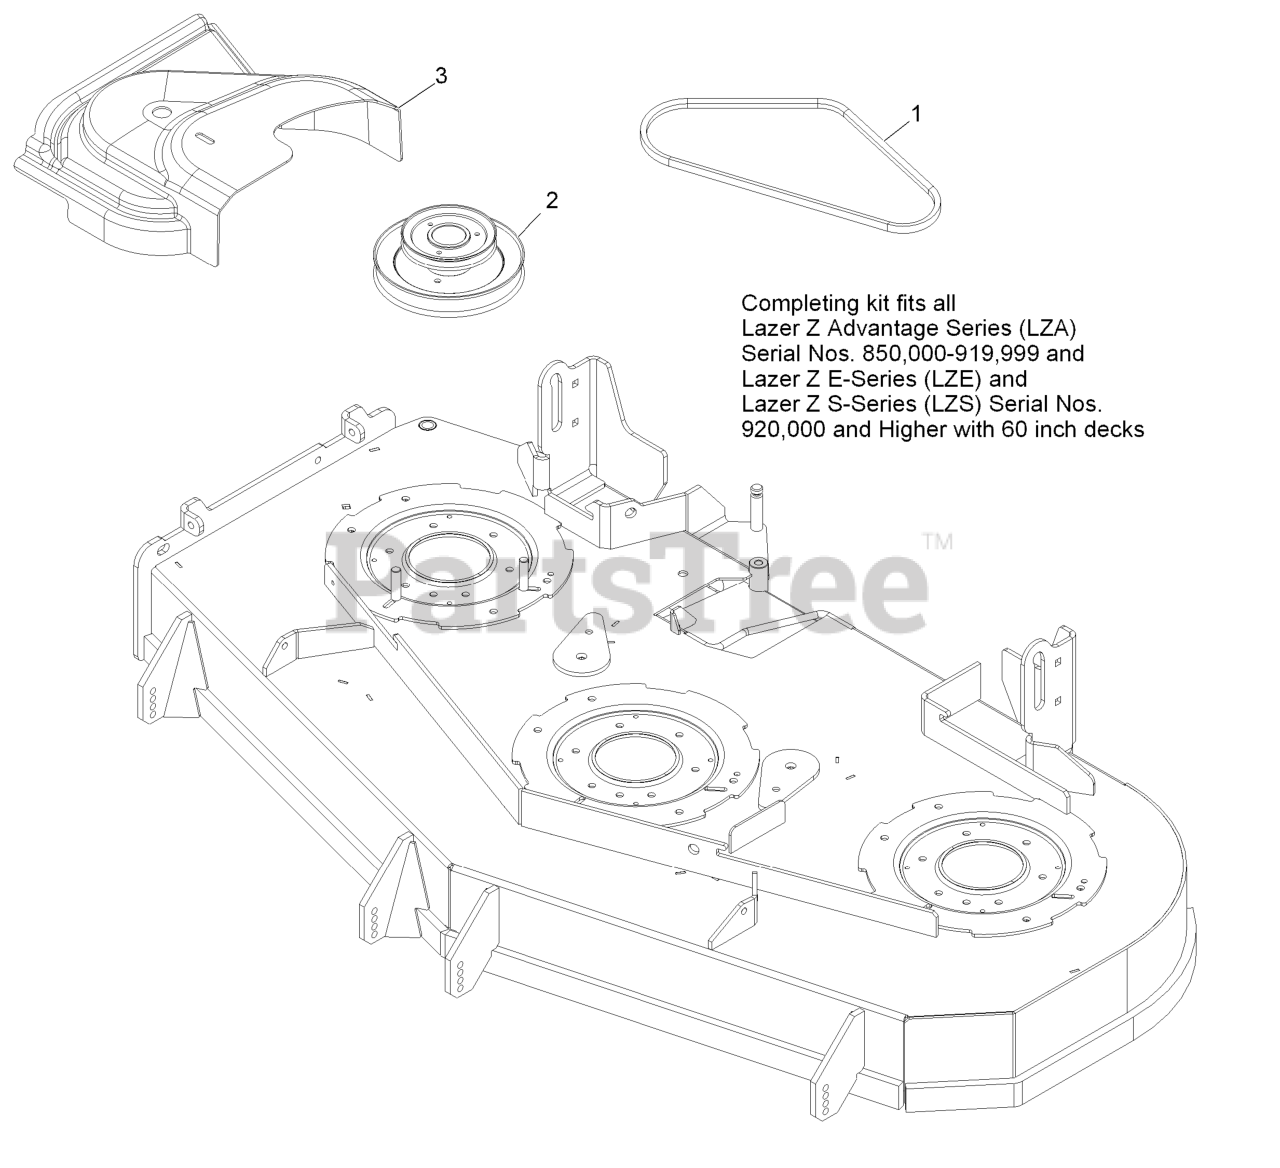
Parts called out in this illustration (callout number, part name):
1	Belt, Blower Drive 60
2	Jackshaft,Uv Drive 604 Splined
3	Cover,Belt Uv 60
